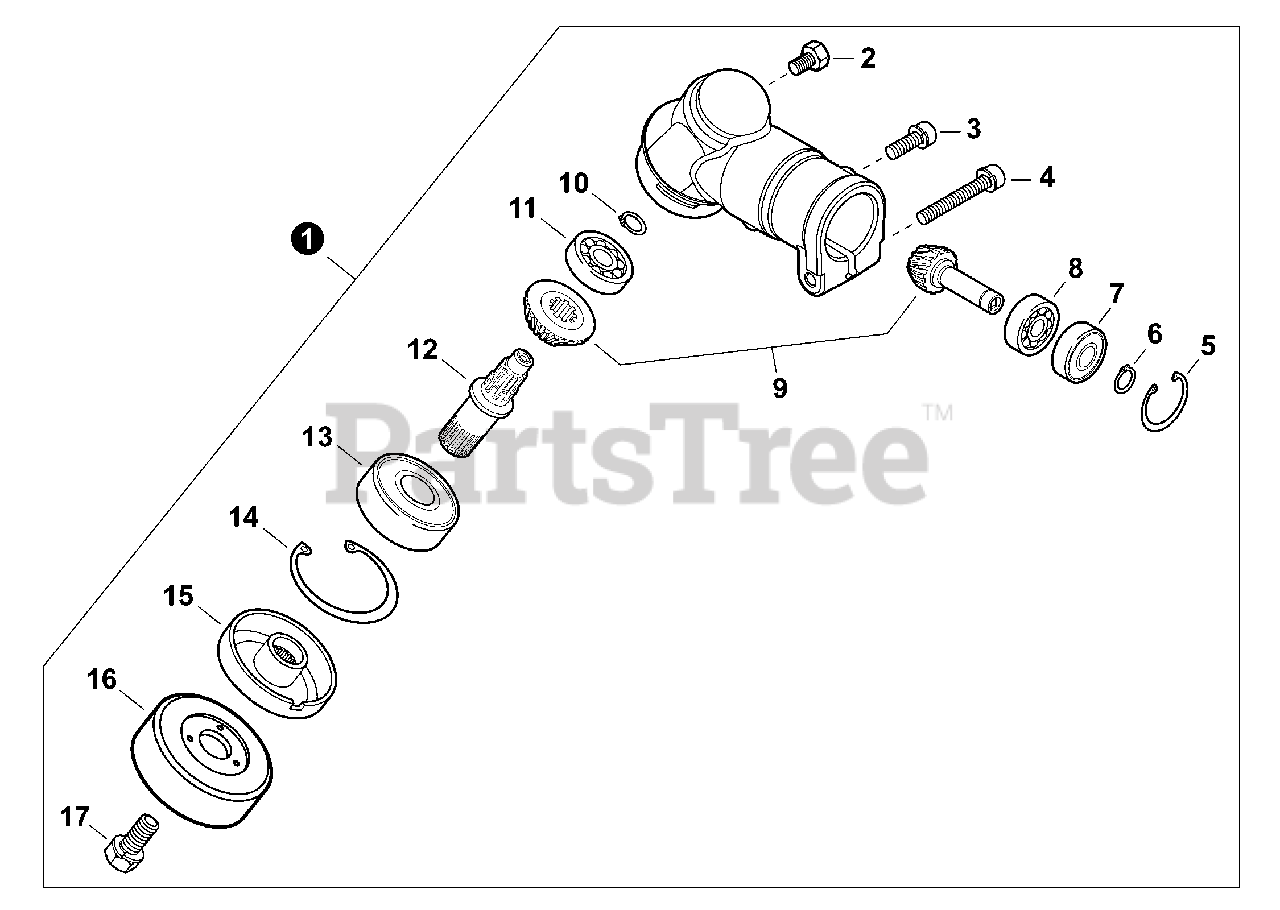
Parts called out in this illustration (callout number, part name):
1	GEAR CASE ASSY
2	BOLT M8×8
3	SCREW 5×12
4	BOLT 5×35
5	RING, SNAP 24
6	RING, SNAP 9
7	BEARING, BALL 609
8	BEARING, BALL 609
9	GEAR SET
10	RING, SNAP 6
11	BEARING, BALL 626 DDU
12	SHAFT, GEAR
13	BEARING, BALL 6000DDU
14	RING, SNAP 26
15	PLATE, ADAPTOR - UPPER
16	GUARD, BOLT
17	BOLT 7
